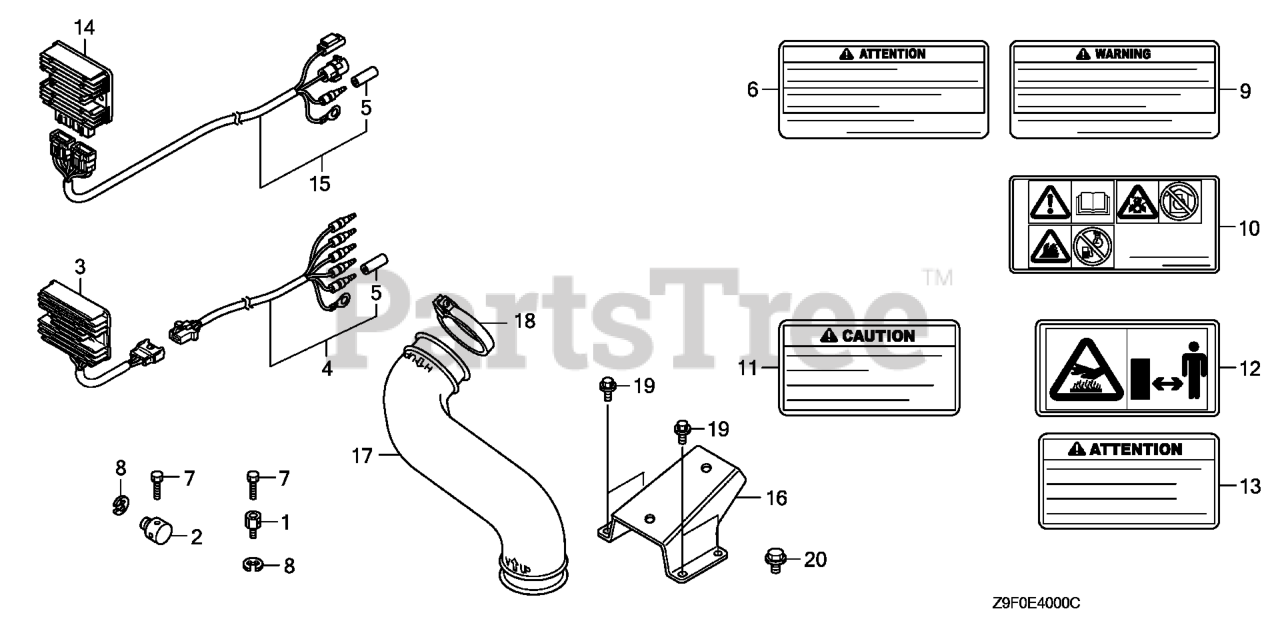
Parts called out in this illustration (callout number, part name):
5	PLUG, CONNECTOR (OUTER) (ENGINE NO.)
6	MARK, OPERATOR CAUTION (FRENCH)(MADE IN JAPAN)
10	MARK, OPERATOR CAUTION (PICTOGRAPH)
11	MARK, EX. CAUTION (ENGLISH)
12	MARK, EX. CAUTION (PICTOGRAPH)
13	MARK, EX. CAUTION (FRENCH)
14	RECTIFIER ASSY., REGULATOR (30A)
15	SUB-WIRE HARNESS ASSY.
